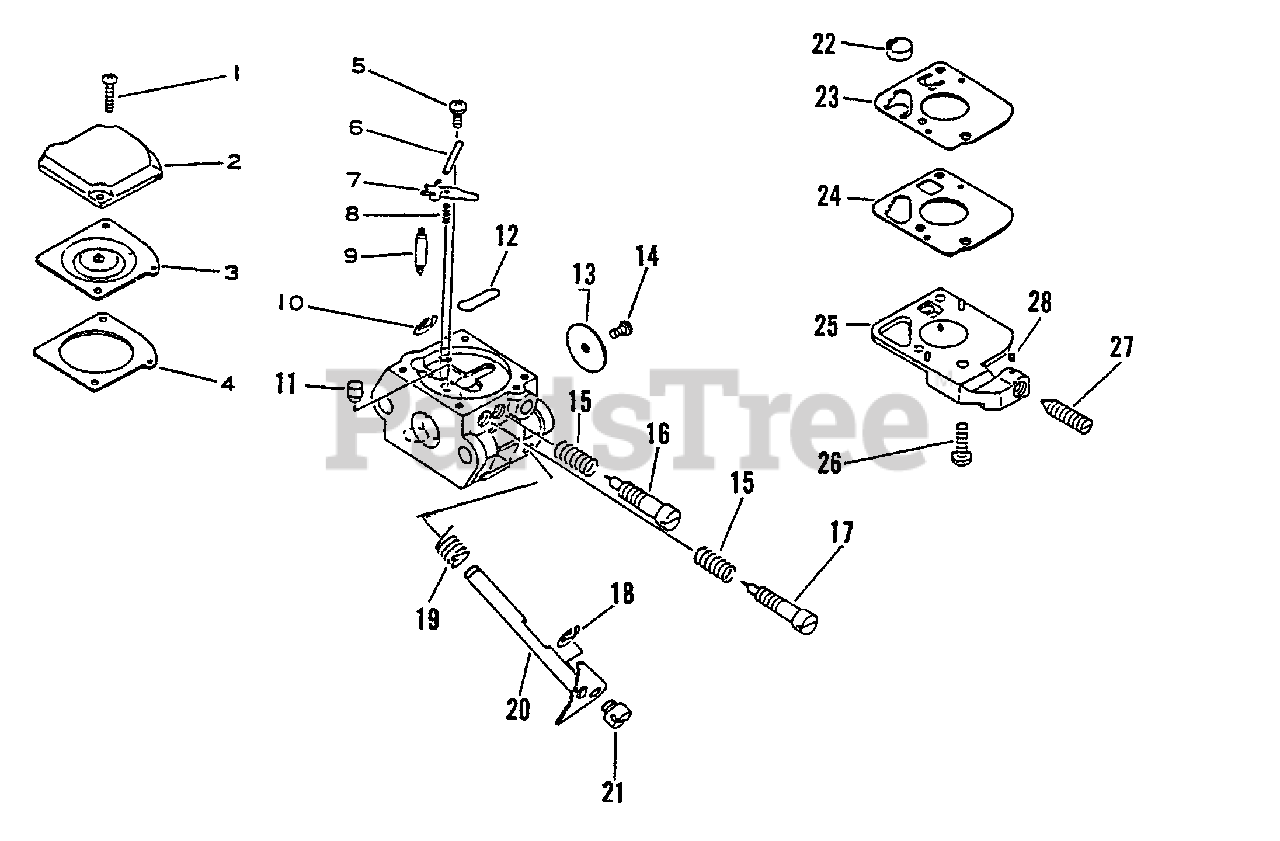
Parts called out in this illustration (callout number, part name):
2	Cover, Diaphragm
3	Diaphragm
4	Gasket, Metering Diaphragm
6	Pin
7	Lever, Metering Cham
8	Spring, Coil
9	Valve, Needle
11	Nozzle, Check Valve
12	Plug, Welch
13	Valve, Throttle
15	Spring, Coil
16	Needle, Hign Speed
17	Needle, Idle
19	Spring, Throttle Return
20	Shaft, Throttle
22	Strainer
23	Diaphragm, Fuel Pump
24	Gasket, Friction
25	Cover, Pump
27	Screw, Idle Adjust
28	Piece, Friction
